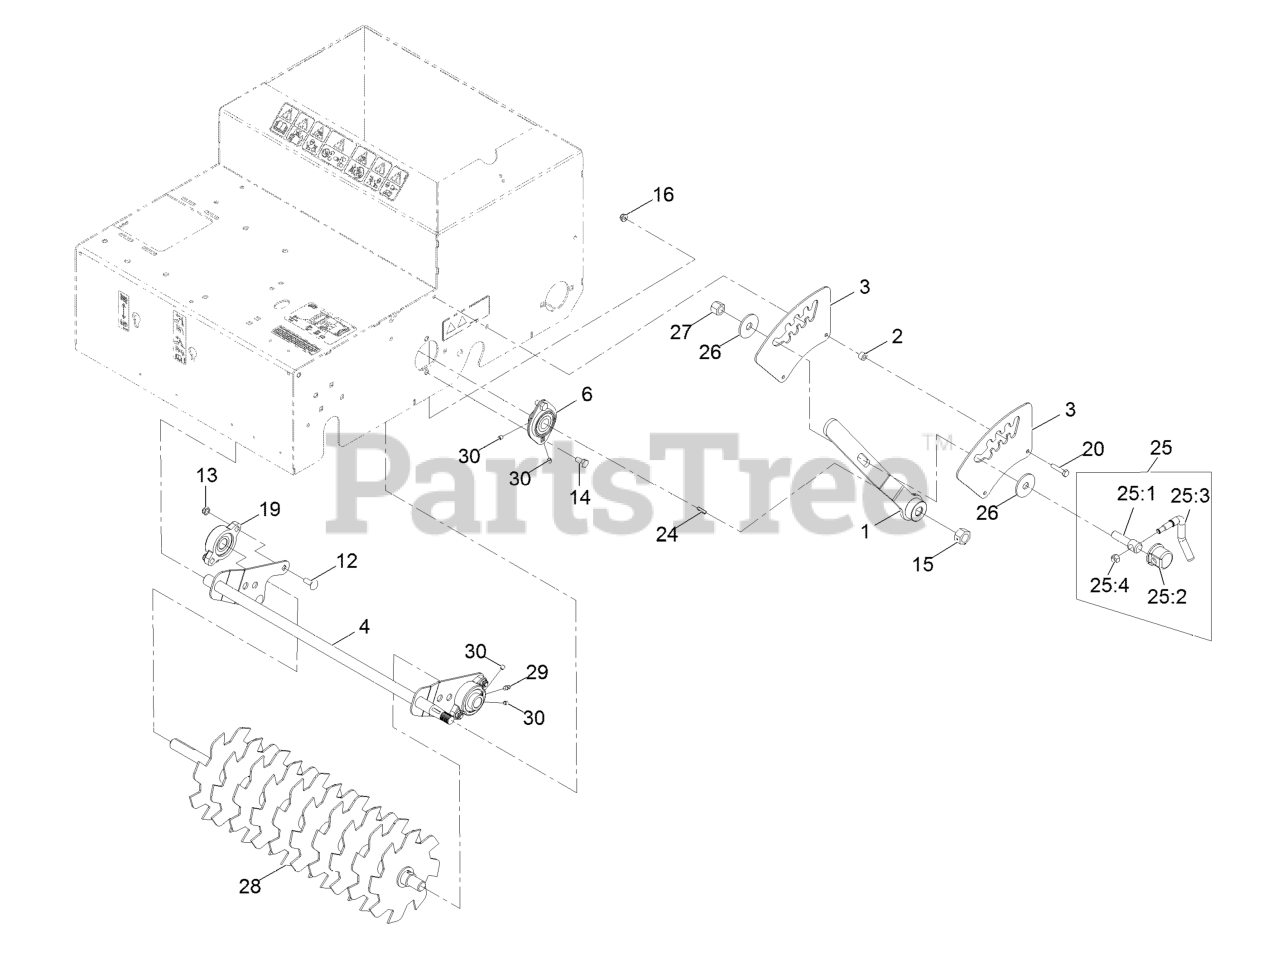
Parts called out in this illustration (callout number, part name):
1	HANDLE-HEIGHT
3	PLATE-HEIGHT
4	PIVOT-HEIGHT
6	BEARING
12	SCREW-CARR
13	NUT-LOCK, NI
14	SCREW-HH
15	NUT-BLADE
19	BEARING-FLANGE
20	SCREW-HH
24	KEY-WOODRUFF
25	LEVER ASM
25:1	SCREW-LOCK
25:2	CAP-LOCK
25:4	NUT-LOCK, NI
26	WASHER-THRUST
27	NUT-LOCK, NI
28	SLICER SHAFT ASM
29	FITTING-GREASE
30	SCREW-SET, HSH
